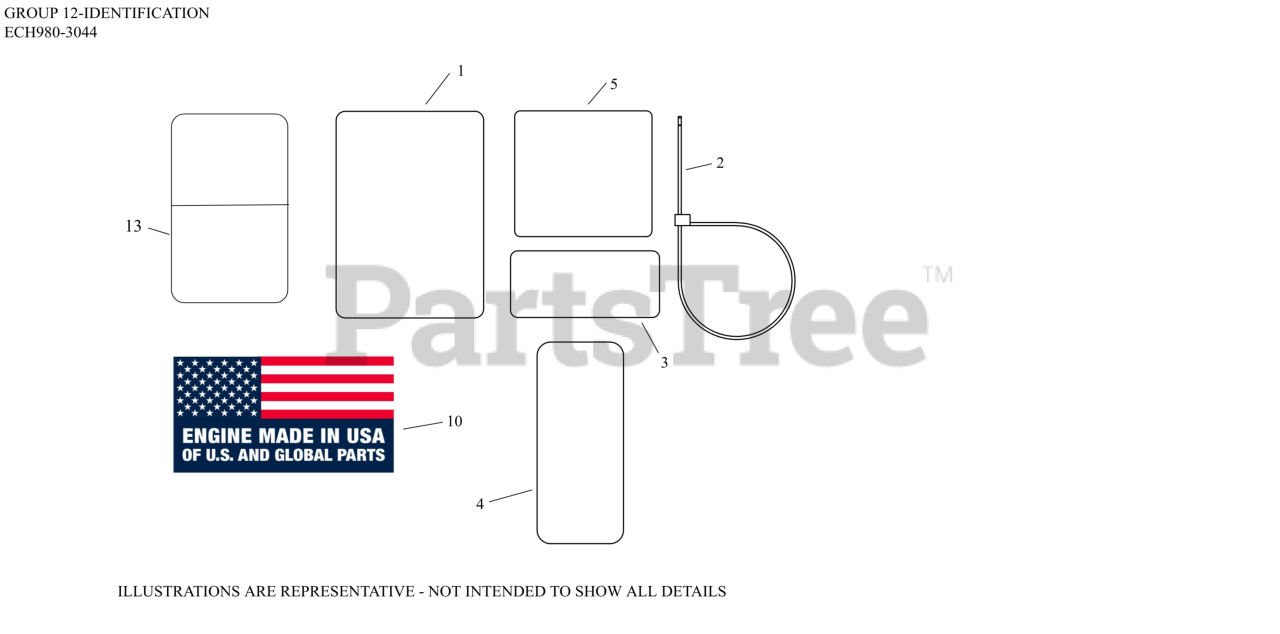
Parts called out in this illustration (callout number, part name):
1	LABEL, CLEAR LAMINATION
3	LABEL, EFI FUEL FILTER
4	LABEL, CANADIAN COMPLIANCE
5	DECAL, HORSEPOWER & DISPLACEMENT
10	DECAL, USA
13	HOT SURFACE DECAL
